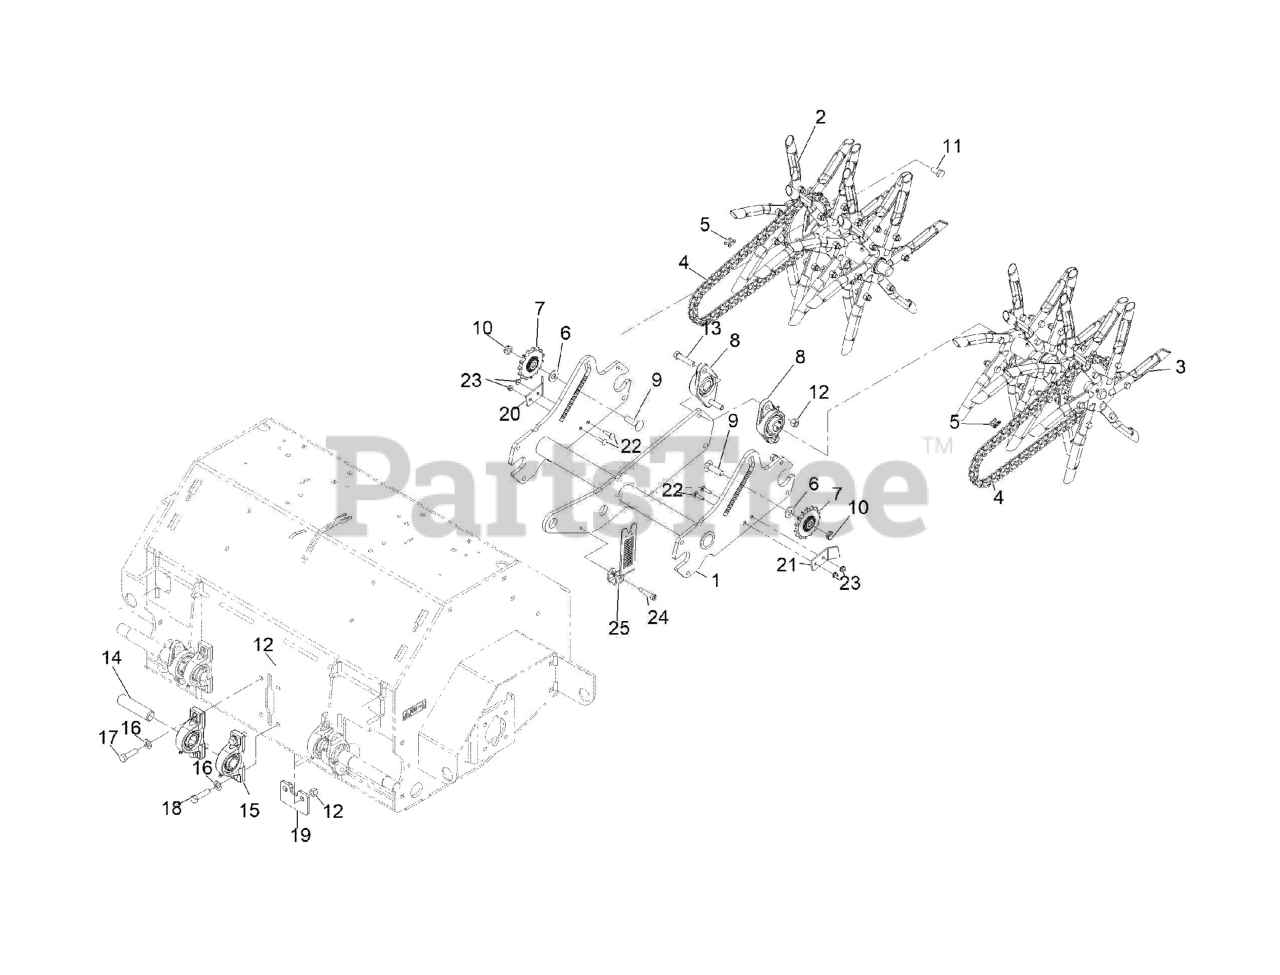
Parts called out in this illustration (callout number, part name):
1	Arm-Trail
2	ASM-TINE WHEEL, RH
3	ASM-TINE WHEEL, LH
4	CHAIN-ROLLER
5	LINK-CONNECTING
6	WASHER-THRUST
7	SPROCKET-IDLER, 15T
8	BEARING-FLANGE, 2 BOLT
9	SCREW-CARR
10	NUT-HEX
11	SCREW-HH
12	NUT-LOCK, NI
13	SCREW-HH
15	BEARING-PILLOW BLOCK
16	WASHER-FLAT
18	SCREW-HH
19	PLATE-DOWNSTOP
20	GUARD-CHAIN, RH
21	GUARD-CHAIN, LH
22	SCREW-CARR
24	SCREW-HSH
25	Bracket-Control, Depth
